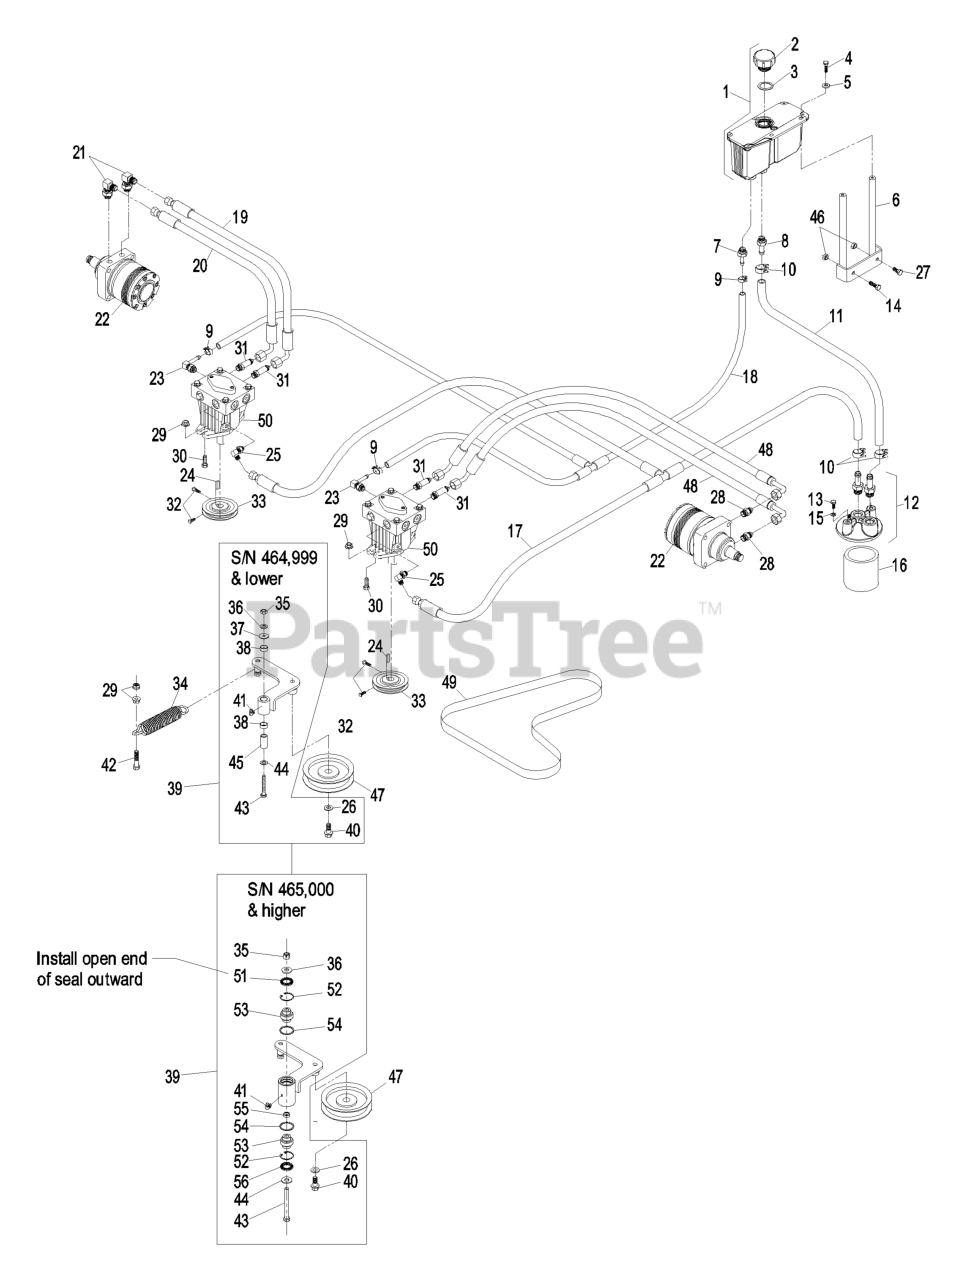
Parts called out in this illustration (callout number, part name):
1	HYD RESERVOIR ASM
2	Cap-Reservoir, HYD
3	GASKET-CAP
4	SCREW-HH
5	WASHER-FLAT
6	STAND-RESERVOIR
7	ADAPTER-STRAIGHT
8	ADAPTER-STRAIGHT
9	CLAMP-HOSE
10	CLAMP-HOSE
11	HYD HOSE ASM
12	FILTER HEAD ASM
13	SCREW-HH
14	SCREW-HH
15	WASHER-LOCK
17	HYD HOSE ASM
18	HYD HOSE ASM
19	HOSE-REAR, RH
20	HOSE-FRONT
21	FITTING-HYD, 90 DEG
22	MOTOR-WHEEL
23	ELBOW-90 DEG
25	FITTING-ELBOW, 90 DEG
26	WASHER-FLAT
27	SCREW-HH
28	FITTING-STRAIGHT
29	NUT-HHF, WHIZ
30	SCREW-HH
31	ADAPTER-STR, LONG
32	SCREW-SET
35	NUT-LOCK, NI
36	WASHER-BELLEVILLE
37	WASHER
38	SLEEVE-BEARING
40	SCREW-HHF
41	FITTING-GREASE, 90 DEG
42	SCREW-HH
43	SCREW-HH
44	WASHER-FLAT
45	BUSHING
48	HOSE-LH
49	BELT-COG
50	PUMP-HYD
51	SEAL-LIP, SINGLE
52	RING-SNAP
53	BEARING-SPHERICAL
54	O-RING
55	SPACER
56	SEAL-LIP, DOUBLE
